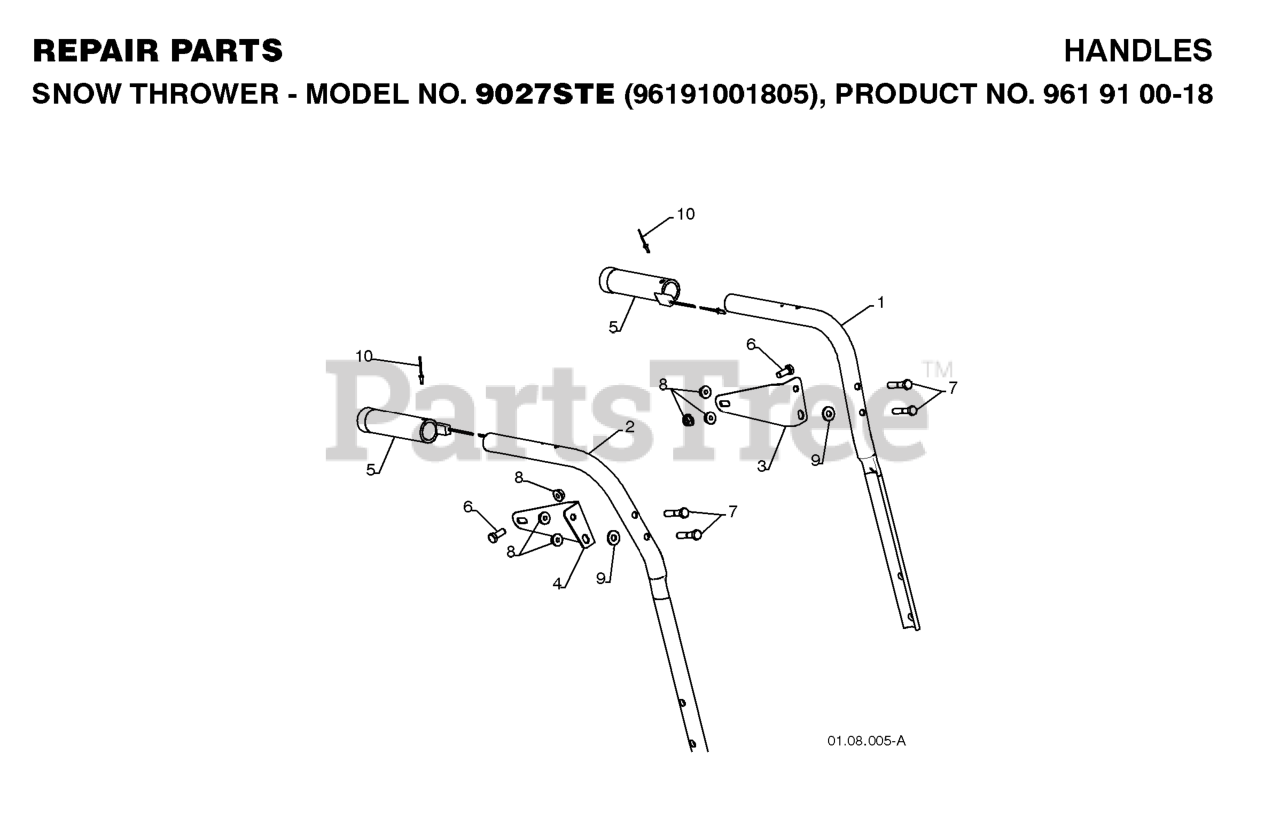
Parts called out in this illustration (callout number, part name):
1	TUBE.HANDLE.PLOW.LH.BLACK
2	TUBE.HANDLE.PLOW.RH.BLACK
3	BRKT.PANEL.LH.INT
4	BRKT.PANEL.RH.INT
5	GRIP.HANDLE.HEATED
6	BOLT.FIN.HEX.5/16-18X3/4
7	HEX BOLT
8	NUT.LOCK.5/16-18
9	WASHER.20X8.5
10	RIVET.POP.1/8X
